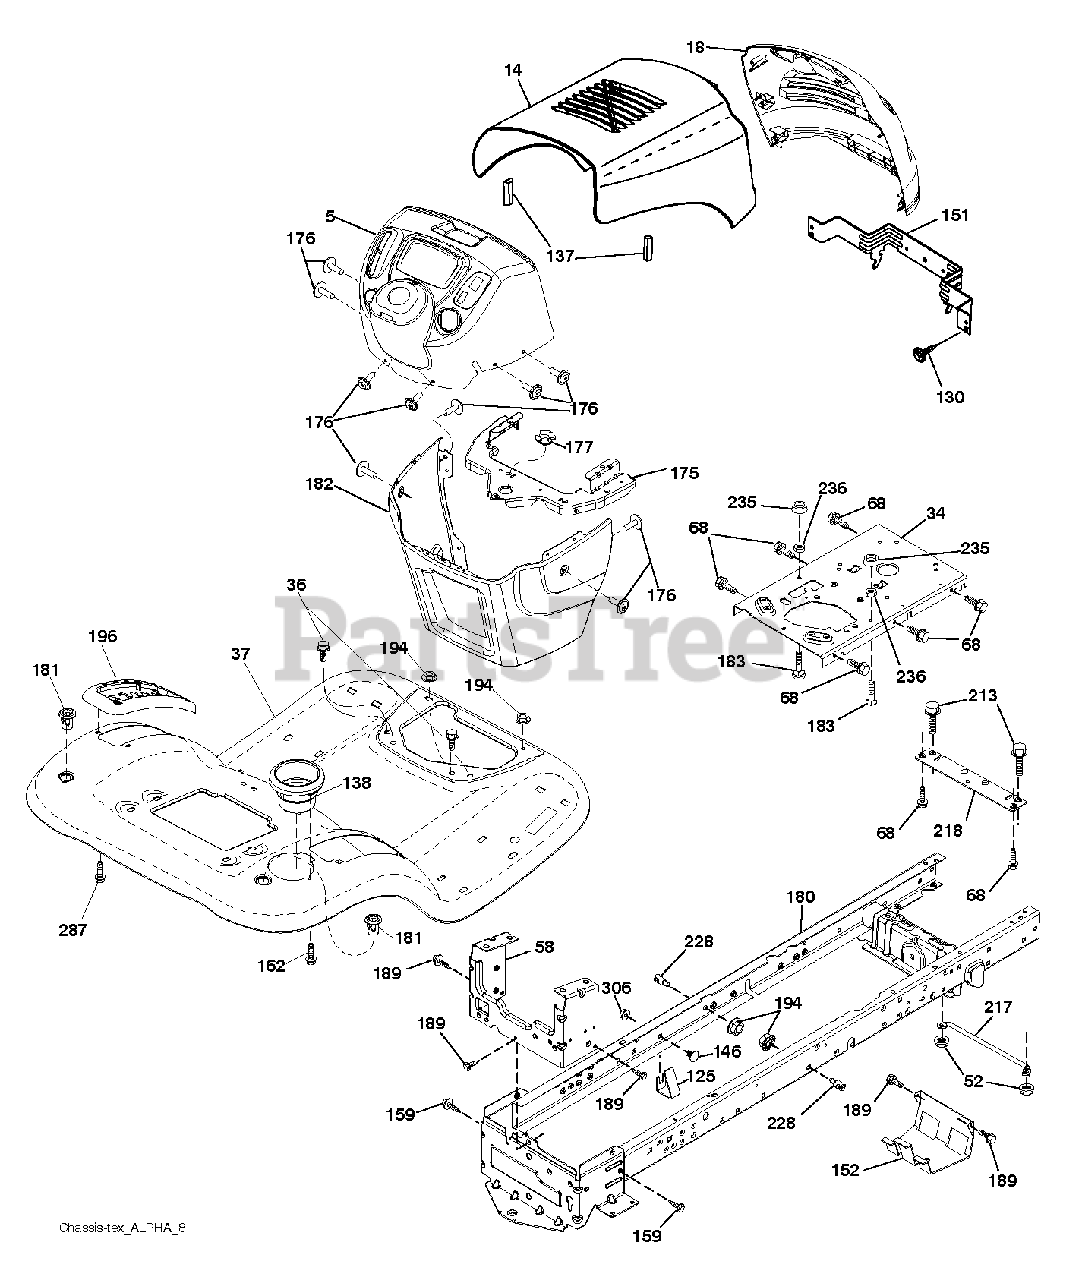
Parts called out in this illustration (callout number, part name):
5	DASH.P/L.TEX.CBL.CL.N/CHK.BLAC
18	GRILLE.ALPHA.LT.NO LI
34	PLATE.ENGINE.WELDED.CHASSIS
36	SCREW 5/16"
52	LOCKNUT
58	DRAWBAR UPPER 2PC SMALL FENDER
68	SCREW LT
125	CLIP.FUEL.LINE
130	SCREW.#10 X 0.750.BOS (2 2)
137	BUMPER.HOOD.LARGE.1.75"
138	CUPHOLDER.TL.TEX.BLACK
146	BOLT.RDHD.SHT.SQNK.3/8-16X5/8
151	BRACKET.PIVOT.ALPHA.LT
152	SHIELD.BROWNING.W/TEX
159	SCREW, 3/8-16X3/4
162	SCREW.HI-LO.CONSOLE
175	CROSSMEMBER.LT
176	SCREW.#10-24X5/8.RN.QU
177	BUSHING STEERING
180	CHASS.WLDMNT.TL.12GA/2P.48/54
181	FEND/FTRST.PCH.CPH.NFW
182	DASH.LOWER.LT.CCS
183	BOLT.5/16-18X1-1/4 FULL THD
189	SCREW
194	NUT LOCK HEX FLANGE 5/16-18
196	CONSOLE.ASM.DECKLFT.BL/RBT.TLT
213	BOLT
217	ROD.PIVOT.HOOD
218	X-PIECE.HOOD.STOP.NON/
228	STUD.FASTNER.W/ANTI-ROTATE
235	SPACER FENDER
236	NUT.CENTERLOCK.5/16-
287	SCREW 1/4X20
306	NUT LOCK FLG 3/8-16 UNC
